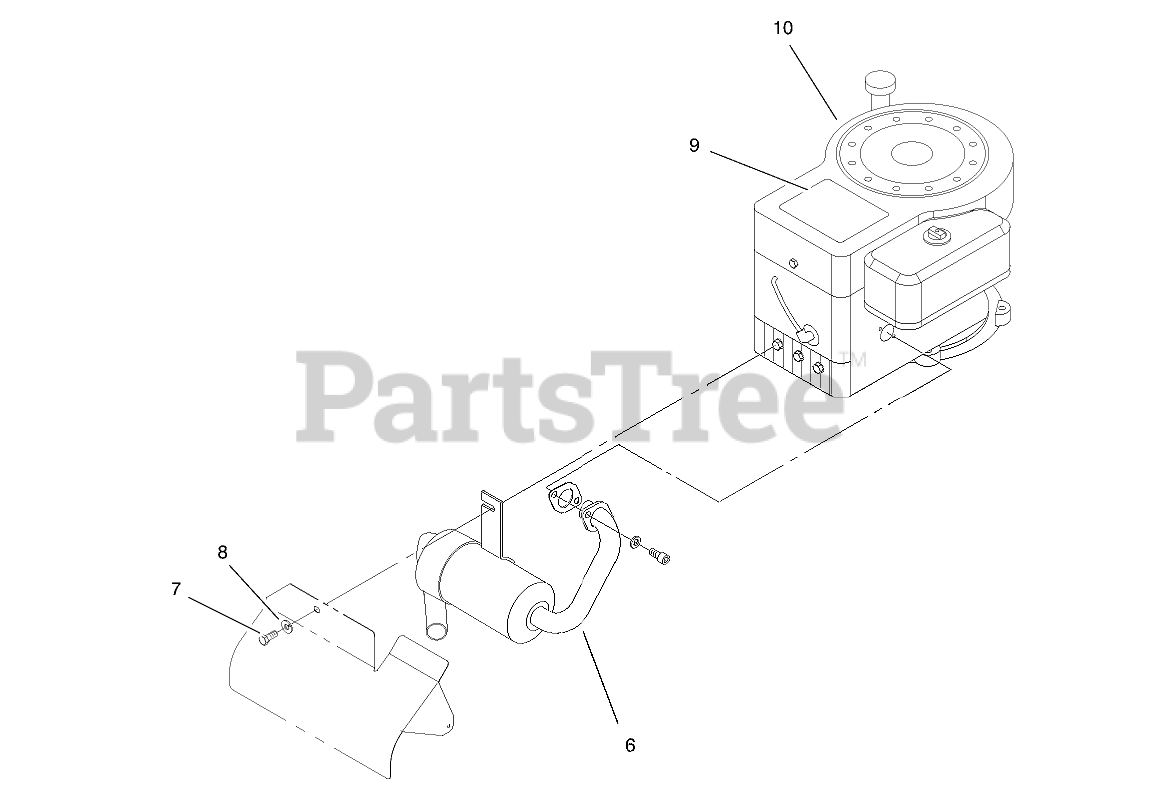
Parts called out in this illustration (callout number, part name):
6	MUFFLER
7	SCREW-HH
8	WASHER-LOCK
9	DECAL - ENGINE
10	Engine-13 Hp B&S Carb)
